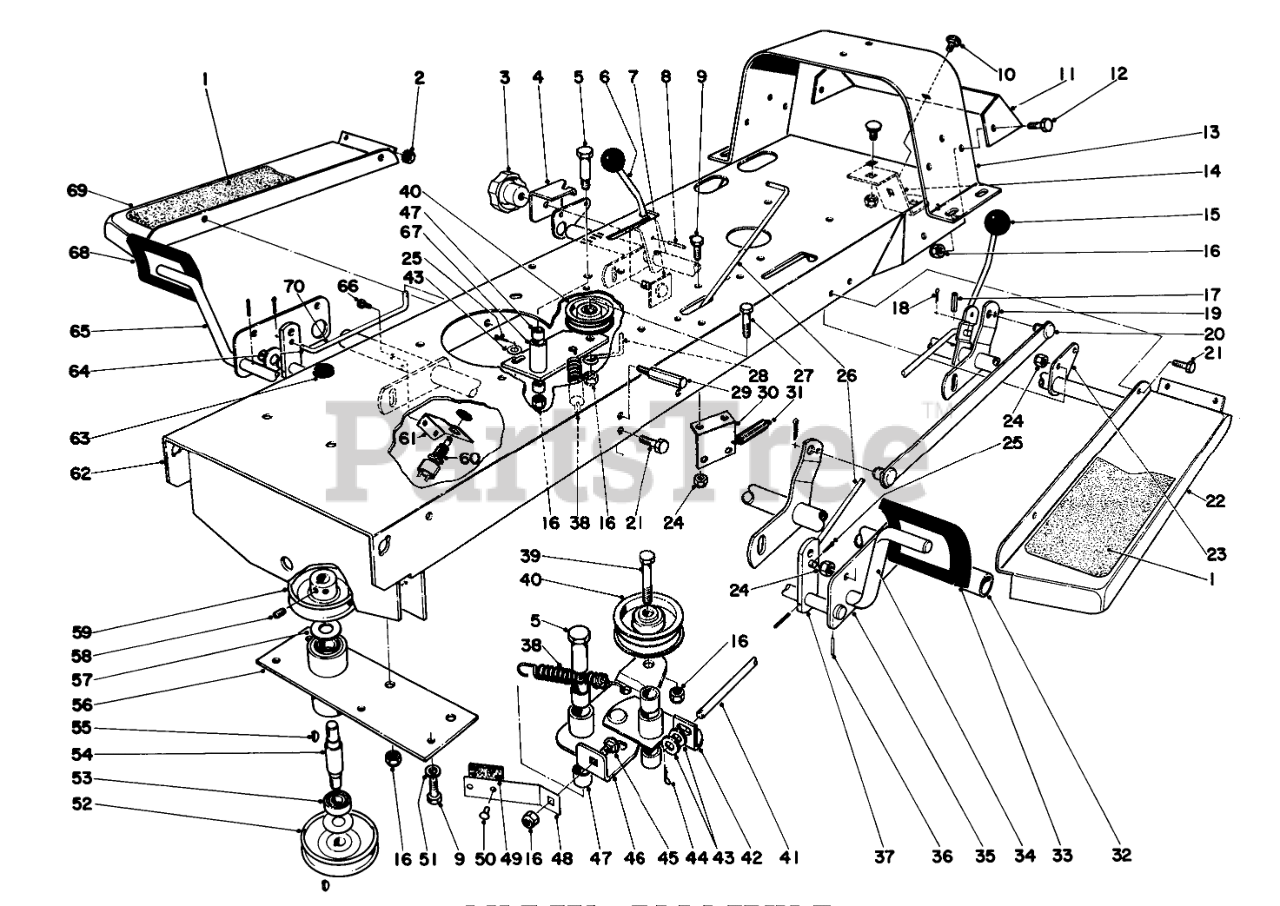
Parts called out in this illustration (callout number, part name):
1	Foot Pad
2	NUT-KEPS
4	Slide Height Adj.
5	Shoulder Bolt
6	Rod Control Hgt. Adj.
7	Knob Plate
8	PIN-ROLL
9	SCREW-HH
10	SCREW-CARR
11	Frame Member Rear
12	SCREW-HH
13	Rear Support
14	Bracket Hitch
15	KNOB-CONTROL
16	NUT-LOCK, CONE
17	1/8 X 1-3/8 ROLL PIN
18	PIN-COTTER
19	Rear Height Adj. Tube
20	Height Adj. Link
21	SCREW-HH
22	Footrest
23	Bracket Tube
24	NUT-LOCK, CONE
25	PIN-COTTER
26	Brake Rod
27	SCREW-HH
28	Belt Retainer
29	Pedal Stop
30	Belt Guide
31	Spring
32	Front Height Adj. Tube
33	CLUTCH PAD
34	Clutch Pedal
35	Plate Tube
36	PIN-SPRING
37	Arm Lever
38	Spring
39	SCREW-HH
40	PULLEY-IDLER
41	Clutch Rod Blade
42	Pivot Bracket
43	WASHER-FLAT
44	PIN-COTTER
45	SCREW-CARR
46	Idler Plate
47	BUSHING
48	Clutch Brake
49	BLADE BRAKE LINING
50	Rivet
51	WASHER-LOCK
52	Pulley
53	Bearing
54	Pulley Shaft
55	KEY-WOODRUFF
56	Pulley Tube
57	Bearing Washer
58	WASHER-FLAT
59	Pulley
60	Switch Spno
61	Switch Mounting Bracket Model 57077
62	Frame Model 57043
63	GROMMET
64	WASHER-FLAT
65	Brake Pedal
66	SCREW-HWHTF
67	Idler Arm
68	PAD-BRAKE
69	Footrest
70	Clutch Rod
